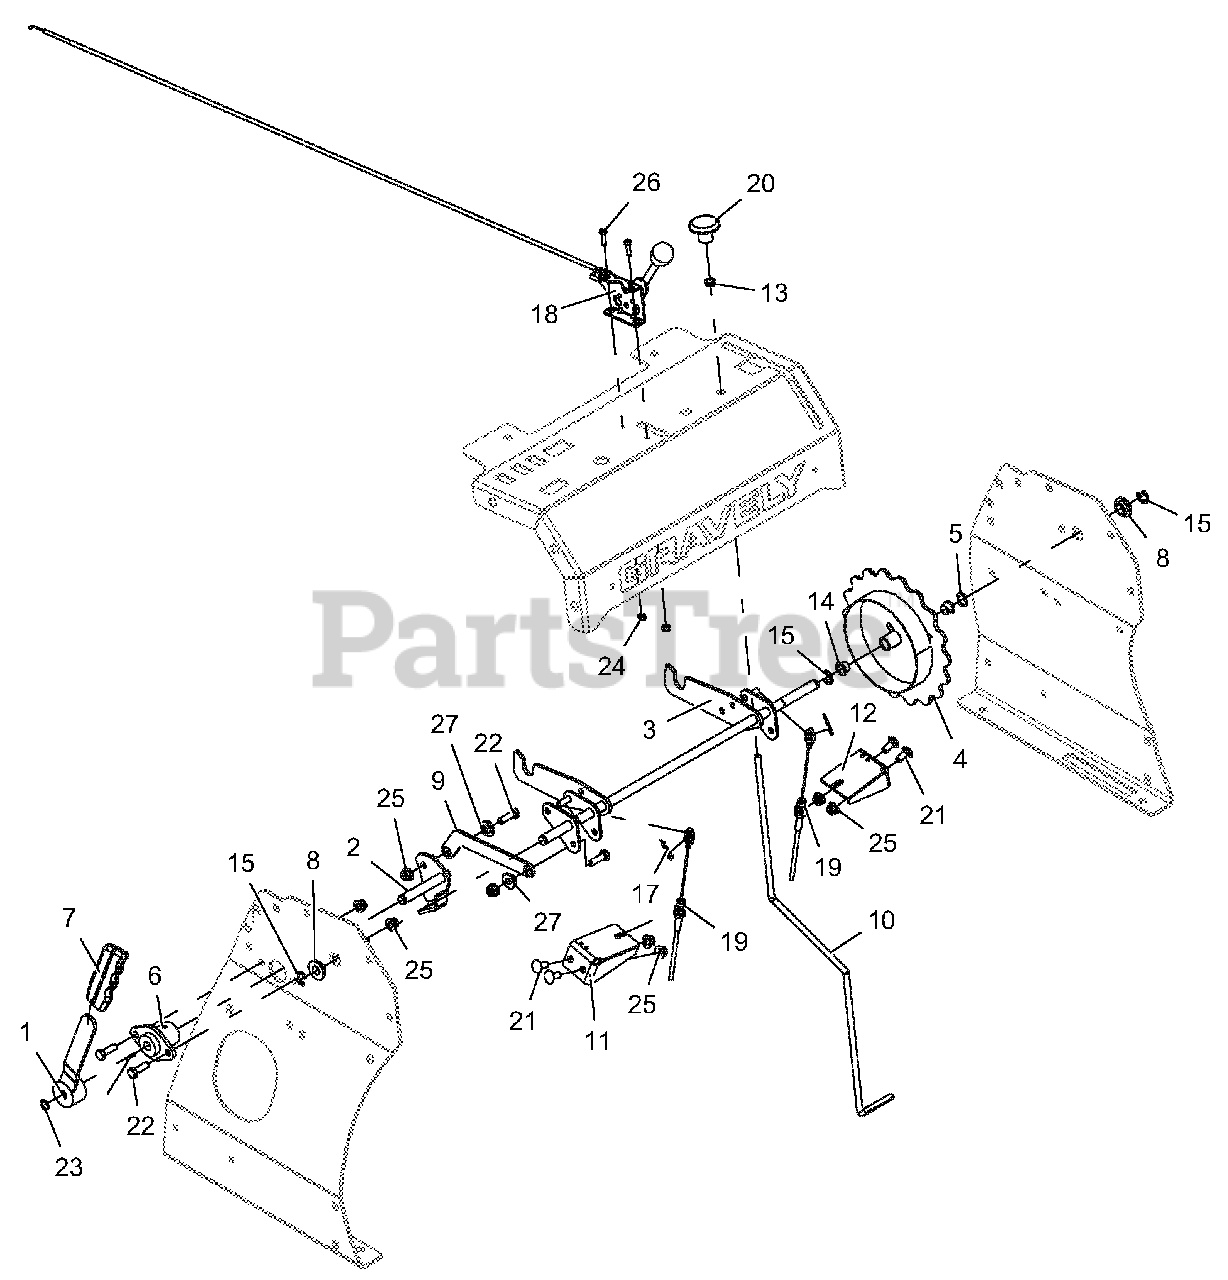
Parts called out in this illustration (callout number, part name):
1	WLDMT, PARKING BRAKE LEVER
2	WLDMT, PARKING BRAKE ACTUATING
3	WLDMT, BRAKE INTERLOCK
4	WLDMT, HEIGHT OF CUT
5	WAVE WASHER .531 x .781 x .125 FH
6	BSHG, FLANGE .500 ID
7	GRIP, PARKING BRAKE (YELLOW)
8	BSHG, FLANGE .515 x .750 x .31 x 1.12
9	LINK, INTERLOCK
10	WIREFORM, TRAILER LOCK
11	BRKT, CABLE MTG.
12	BRKT, LH CABLE MTG
13	BSHG, POLYLINER - .38 SNAPIN
14	BUSHING, POLYLINER - .50 SPLIT
15	RG-RTNG-EXT .500 x .042 (E)
16	KEY, WDRF .13 x .63 HRD#5 GM124545 P
17	PIN, HAIR INT .08 x .18 x 1.18 YWZC
18	CABLE, PRO-CONTROL THROTTLE
19	CABLE, PROSTANCE P. BRAKE
20	KNOB, PUSH -PULL .312-18
21	BLT-RDHDSQNK .31-18 x .75 G5 YWZC
22	BLT-HEX .31-18 x 1.00 GR5 YWZC
23	RG-RTNG-EXT .500 x .050
24	NUT-LK-NYL #10-24 YWZC
25	NUT-LK-NYL-FLG .31-18 YWZC
26	@SCR-MCH 10-24 x .75 HWH YWZC
27	BSHG, FLG .32 x .500 .344 x .880
